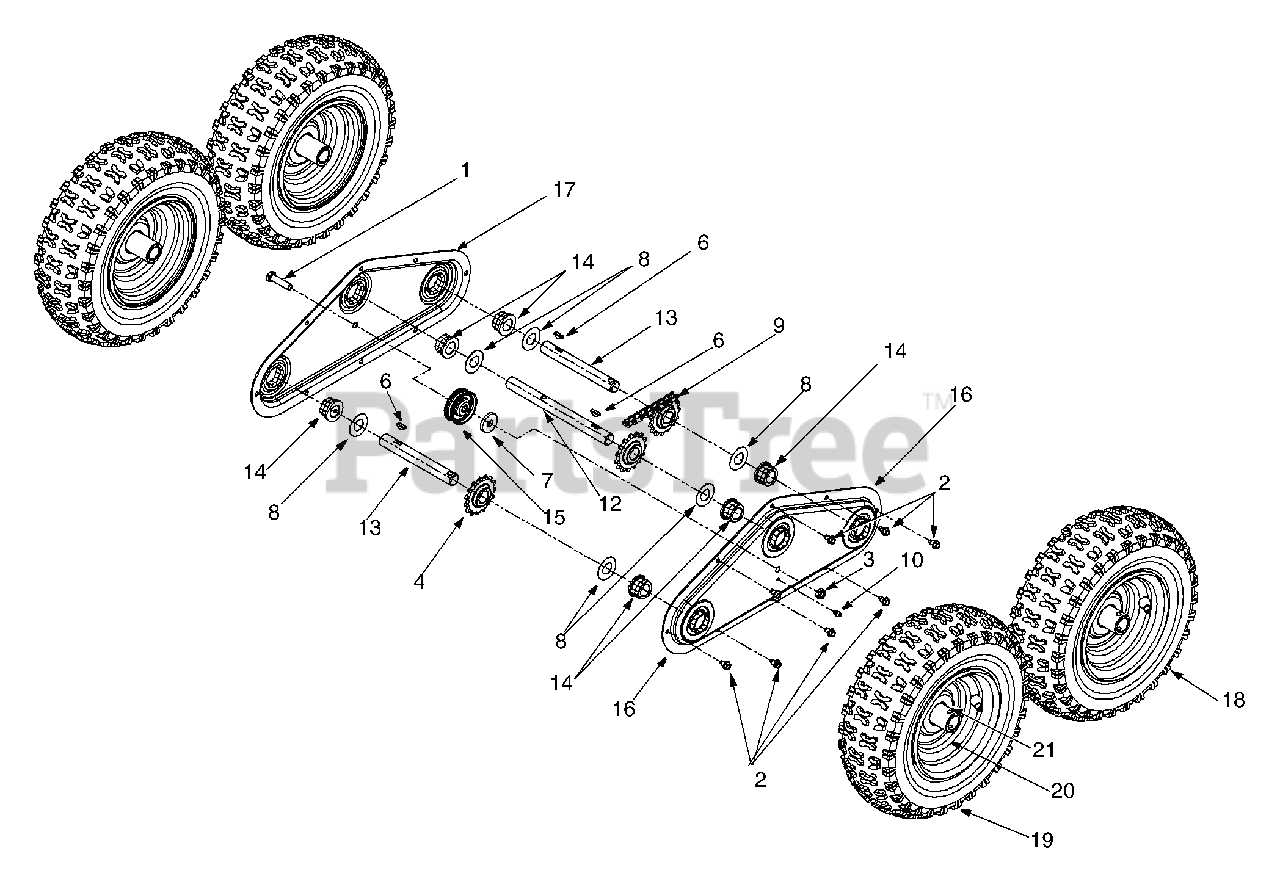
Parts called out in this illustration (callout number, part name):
1	Special Hex Screw: 3/8-24 x 1.5"
2	TT Screw: 1/4-20 x 0.5"
3	Jam Nut
4	Sprocket
6	Key
7	Flat Washer
8	Flat Washer
9	Lubricant: 6in 1
10	Lube Fitting
12	Drive Axle
13	Wheel Axle
14	Hex Flange Bearing
15	Flat Idler
16	Chain Case: Outer, Polo Green
17	Chain Case: Inner, Polo Green
20	Rim Assembly: Oyster Grey
21	Bearing
